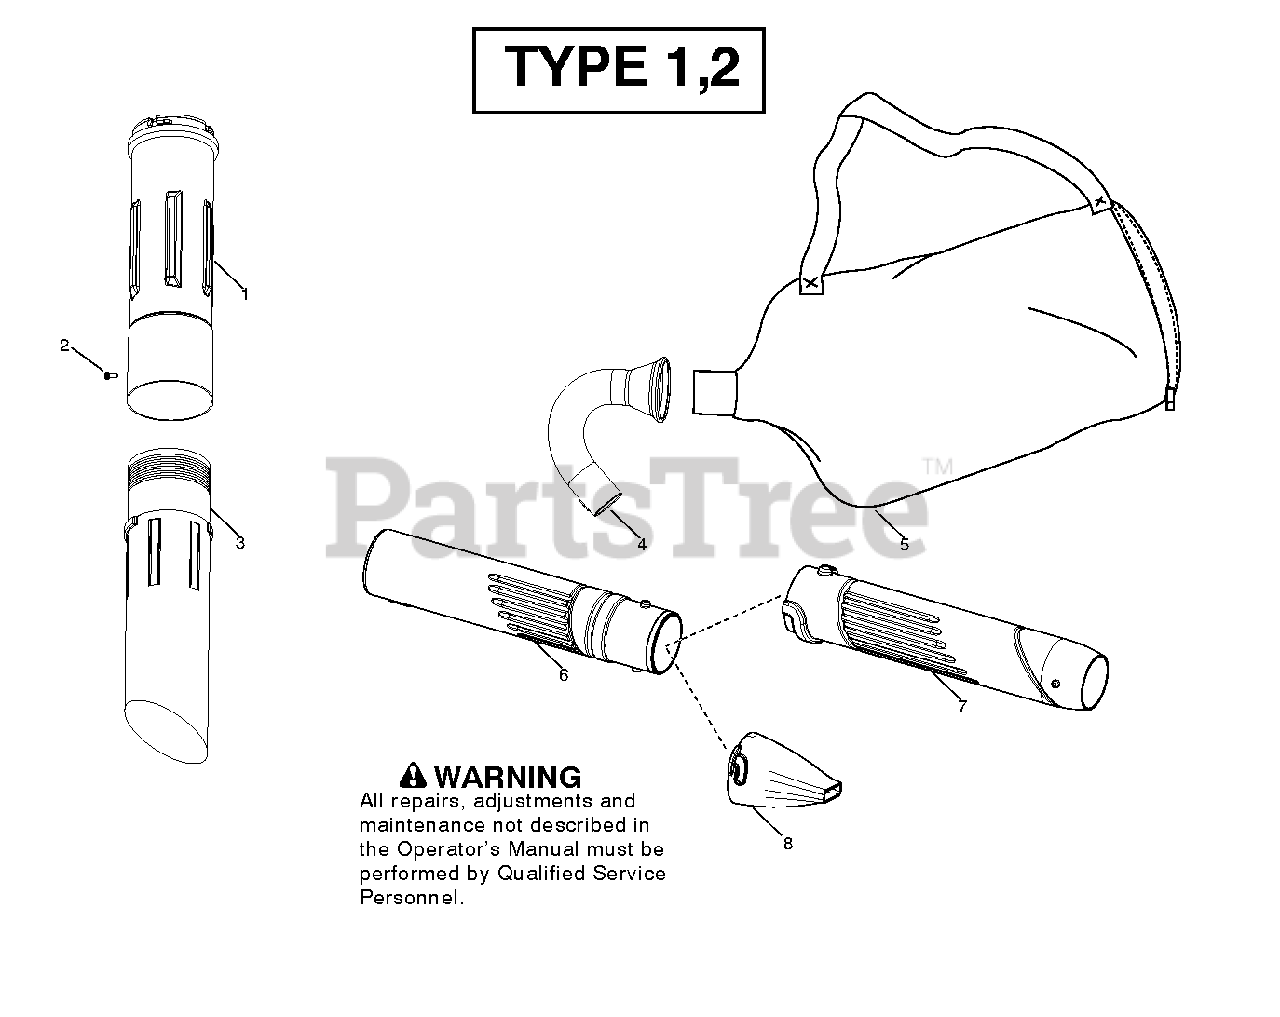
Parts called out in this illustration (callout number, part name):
1	TUBE VAC UPPER BLACK
4	TUBE VACUUM J BLACK
5	ASSY VAC BAG GAS W/STRAP
6	BLOWER TUBE
7	TUBE BLOWER LOW END BLACK
8	NOZZLE BLACK HI SPEED ADAPTOR
